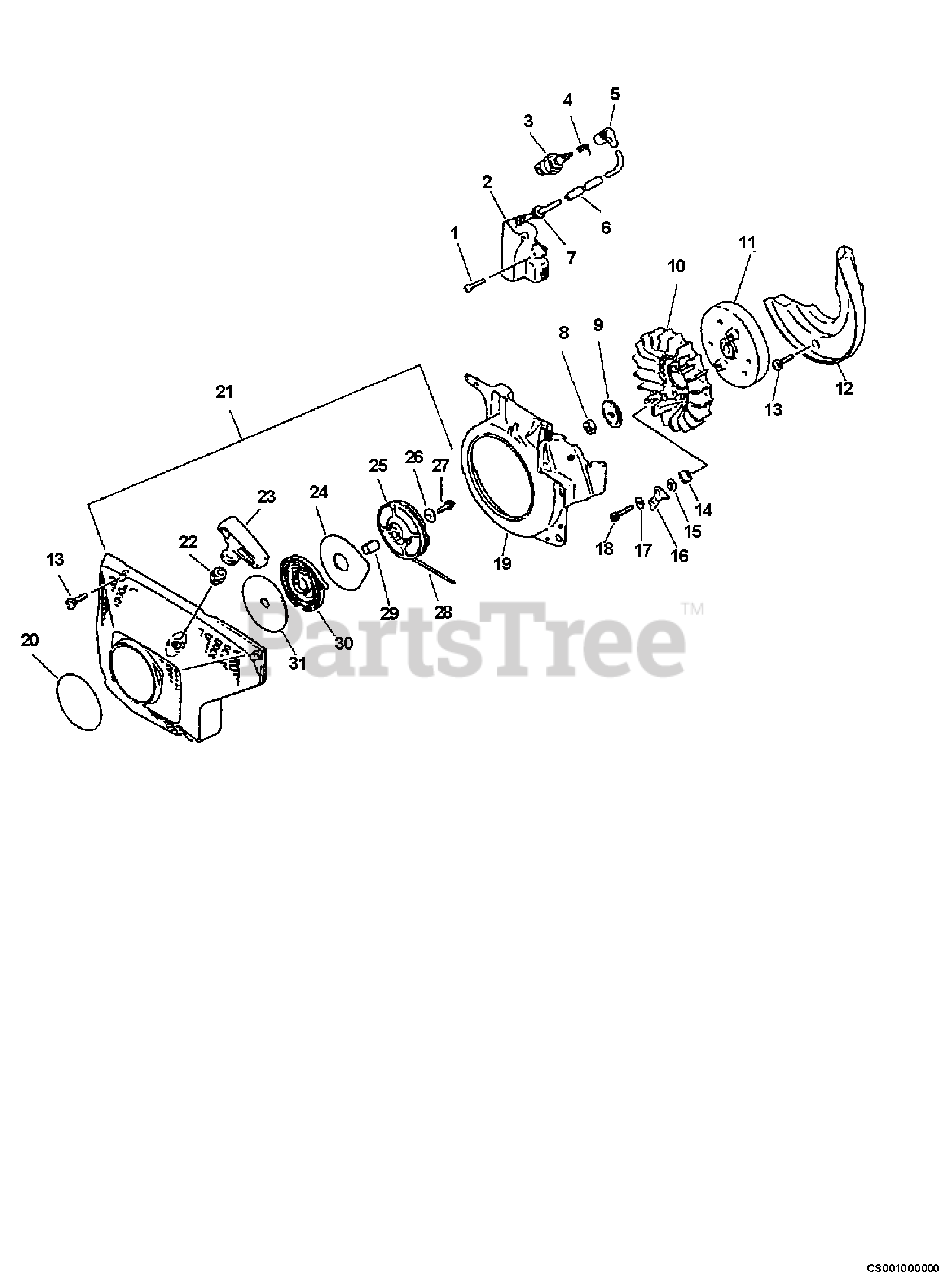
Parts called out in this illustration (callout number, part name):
1	SCREW - 4X20
2	COIL, IGNITION
3	SPARK PLUG -- CJ-6Y
4	TERMINAL, SPARK PLUG CAP
5	CAP, SPARK PLUG
8	NUT - FLANGE
9	WASHER - CUP
11	FLYWHEEL
12	SHIELD, FAN
13	SCREW - 5X20
14	SPRING, RETURN
16	PAWL, STARTER
17	WASHER - 5
18	SCREW - 5X30
19	SHIELD, FAN
20	LABEL - ECHO
21	STARTER ASSY
22	GUIDE, ROPE
23	GRIP, STARTER
24	PLATE, STARTER
25	REEL, ROPE
26	WASHER - 5
27	SCREW - 5X14
28	ROPE, STARTER - 4X950
30	SPRING, REWIND
31	PLATE, STARTER
